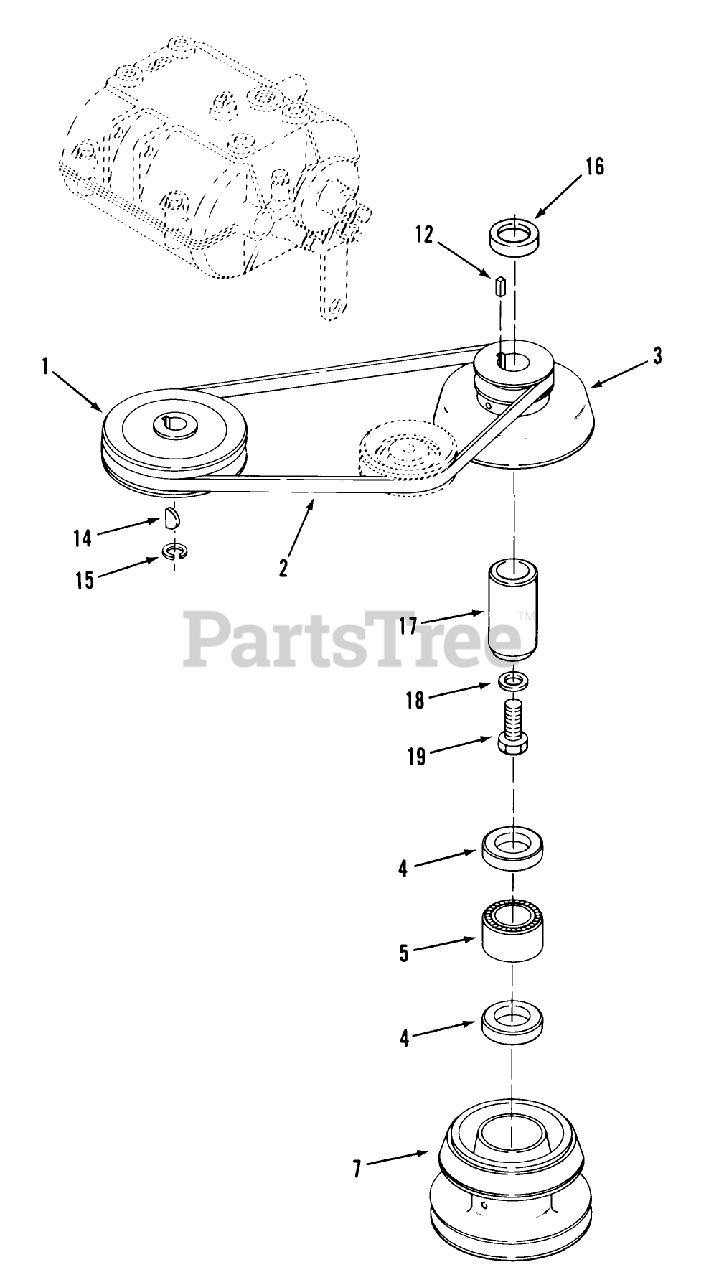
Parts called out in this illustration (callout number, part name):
1	PULLEY
3	Pulley-Engine
4	SEAL-OIL
5	BRG-NEEDLE OPEN END
12	KEY-SQUARE
15	SNAP RING- 5/8 EXT
19	HEX HD CAP SCREW
